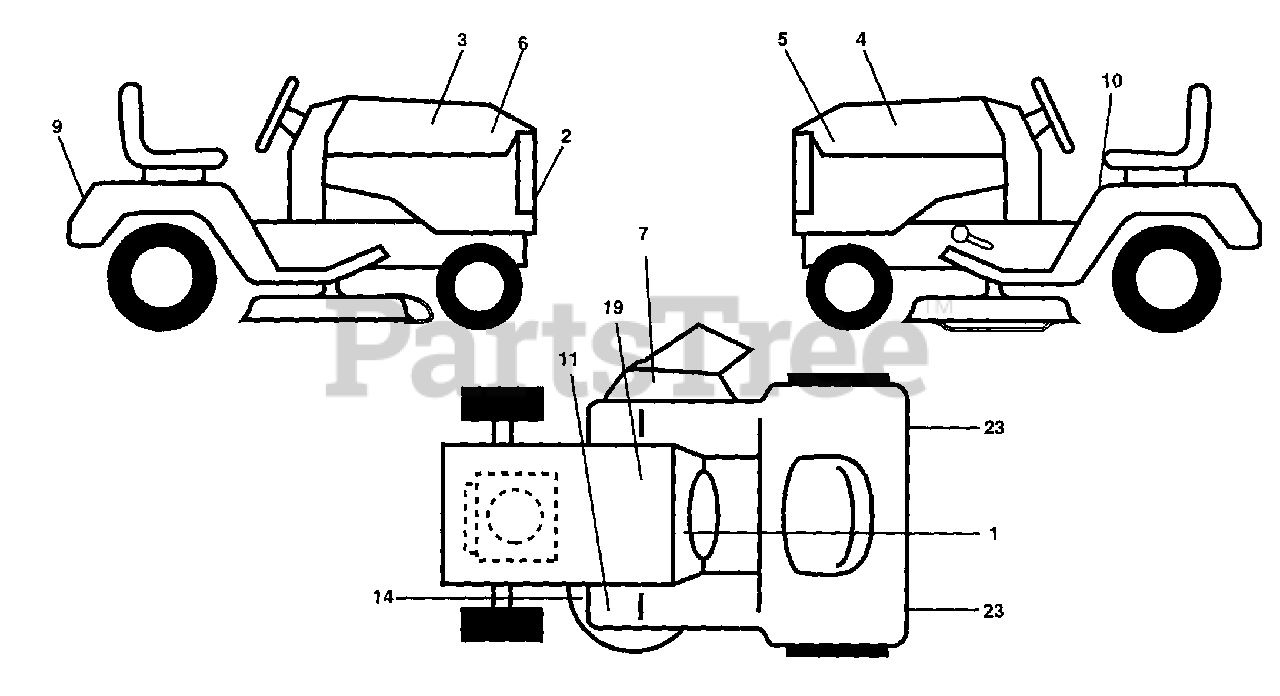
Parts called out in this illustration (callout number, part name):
1	Decal, Operating Instruction
2	Decal, Grille Husqvarna "H" Logo
3	Decal, Hood, RH
4	Decal, Hood, LH
5	Decal, Insert Hood LH GT200 6Sp
6	Decal, Insert Hood RH GT200 6Sp
7	Decal, Warning Multi-Language
9	Decal, Fender
10	Decal, Caution
11	Decal, Clutch/Brake
14	Decal, V-Belt Schematic
19	Decal, Battery
23	Reflector, Taillight
